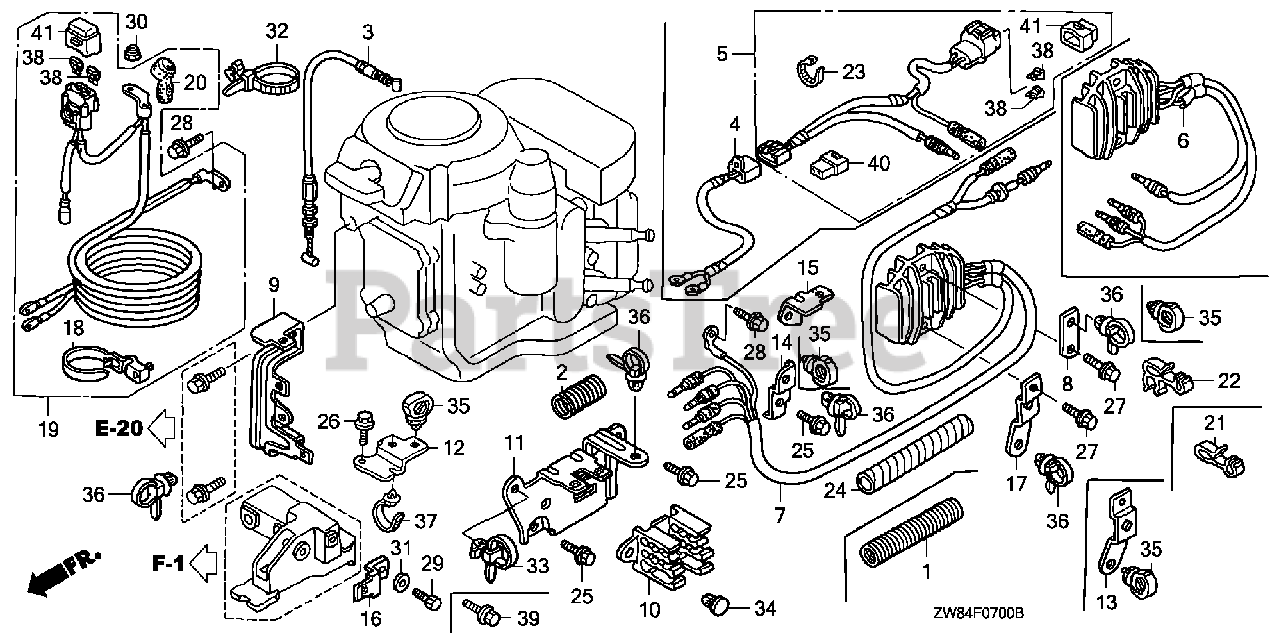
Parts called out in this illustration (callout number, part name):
3	CABLE, NEUTRAL STARTING
7	RECTIFIER ASSY., REGULATOR
8	BRACKET, CLIP F
9	BRACKET, CONNECTOR (A)
10	BRACKET, CONNECTOR (B)
11	BRACKET, CONNECTOR (C)
12	BRACKET, STARTER CABLE
14	BRACKET, CLIP B
15	BRACKET, FUSE CASE
17	BRACKET, E-CLIP
18	BAND, WIRE
19	CABLE ASSY., STARTER
20	COVER, MAGNETIC SWITCH TERMINAL
22	CLAMP, DISTRIBUTOR WIRE
24	TUBE, SPIRAL A
25	BOLT, FLANGE (6X14) (CT200)
26	BOLT, FLANGE (6X14) (CT200)
27	BOLT, FLANGE (6X26) (CT200)
28	BOLT, FLANGE (6X12)
30	NUT, LOCK (6MM)
32	BAND, WIRE
33	STRAP, CABLE (118MM) *NH1L* (BLACK)
34	CLIP, ANCHOR
35	CLIP, HARNESS
36	CLIP, HARNESS BAND (151.5MM) (NATURAL)
37	BAND, WIRE HARNESS (123.5MM) (BLUE)
38	FUSE, BLADE (20A)
41	COVER ASSY., FUSE (20A)
